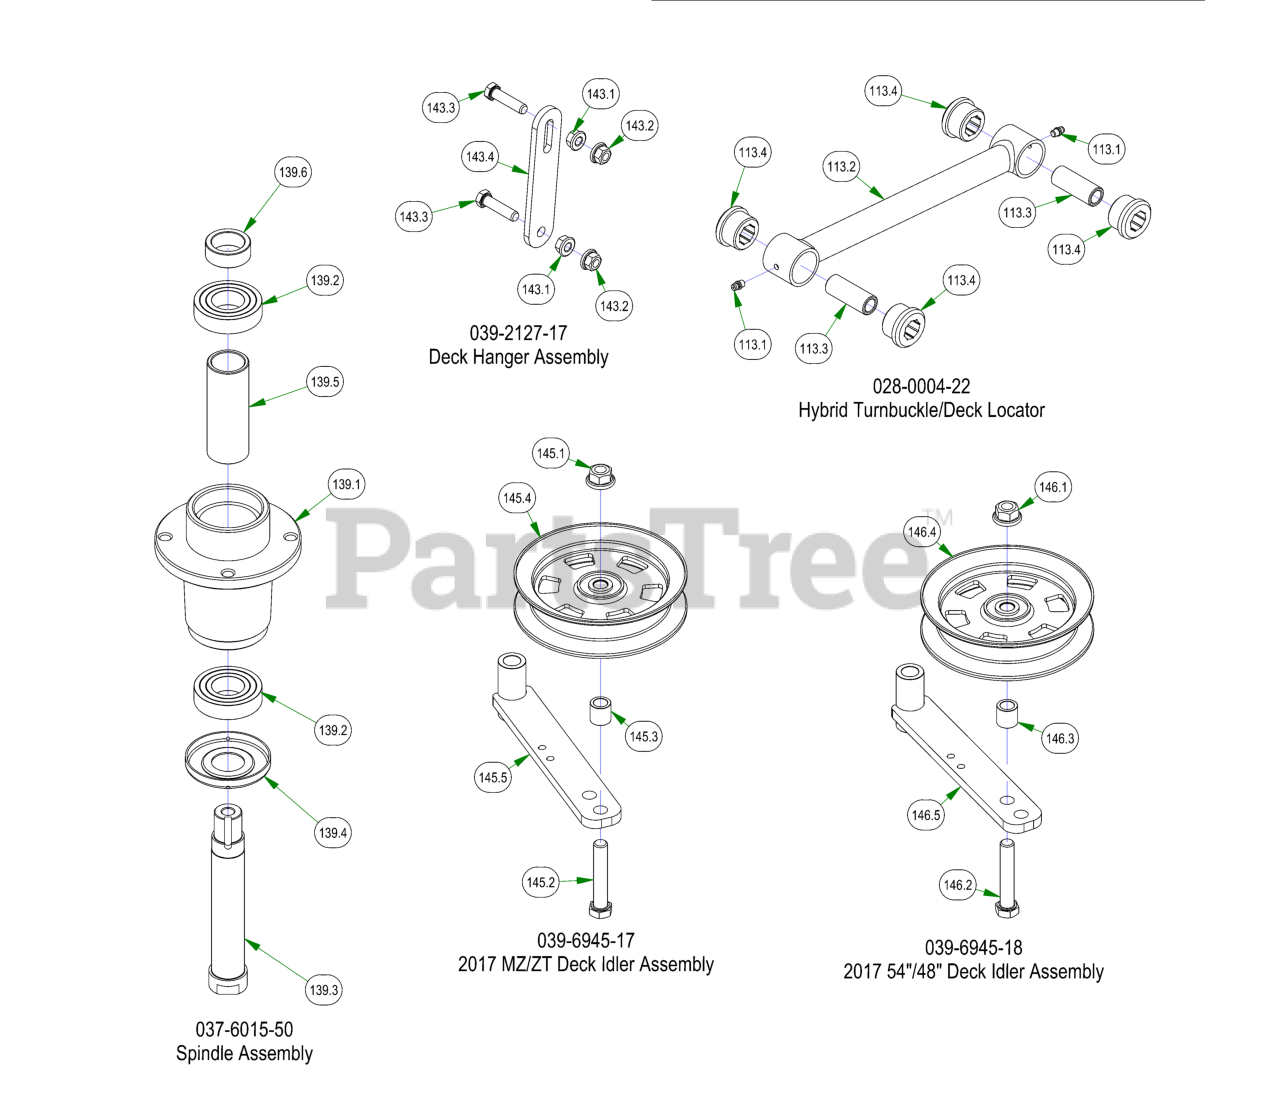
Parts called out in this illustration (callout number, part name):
113	Hybrid Turnbuckle/Deck Locator
113.1	1/4-28 Grease Fitting
113.2	2022 Isolator Turnbuckle Body
113.3	2018 Maverick Bushing Sleeve
113.4	2018 Maverick Bushing
139	Spindle Assembly
139.1	Spindle Housing
139.2	Bearing - 6206
139.3	Spindle Shaft
139.4	Spindle Dust Cap
139.5	Spindle Spacer
139.6	Locking Collar w/ 1/4"-20 Set Screw
143	Deck Hanger Assembly
143.1	3/8-16 HEX SERRATED FLANGE NUT HARD/ZINC
143.2	3/8-16 NYLON INSERT FLANGE LOCKNUT (GR.F) ZINC
143.3	3/8-16 X 1-1/2 HEX CAP SCREW (GR.5) ZINC
143.4	2017 MZ/ZT Deck Hanger
145	2017 MZ/ZT Deck Idler Assembly
145.1	1/2-13 NYLON INSERT FLANGE LOCKNUT ZINC
145.2	1/2-13 X 2-3/4 HEX CAP SCREW (GR.5) ZINC
145.3	.51 ID X .75 OD X .75 LGTH SOLID SPACER ZINC
145.4	5" Idler Pully
145.5	Deck Idler
146	2017 54"/48" Deck Idler Assembly
146.1	1/2-13 NYLON INSERT FLANGE LOCKNUT ZINC
146.2	1/2-13 X 2-3/4 HEX CAP SCREW (GR.5) ZINC
146.3	.51 ID X .75 OD X .75 LGTH SOLID SPACER ZINC
146.4	5" Idler Pully
146.5	Deck Idler
